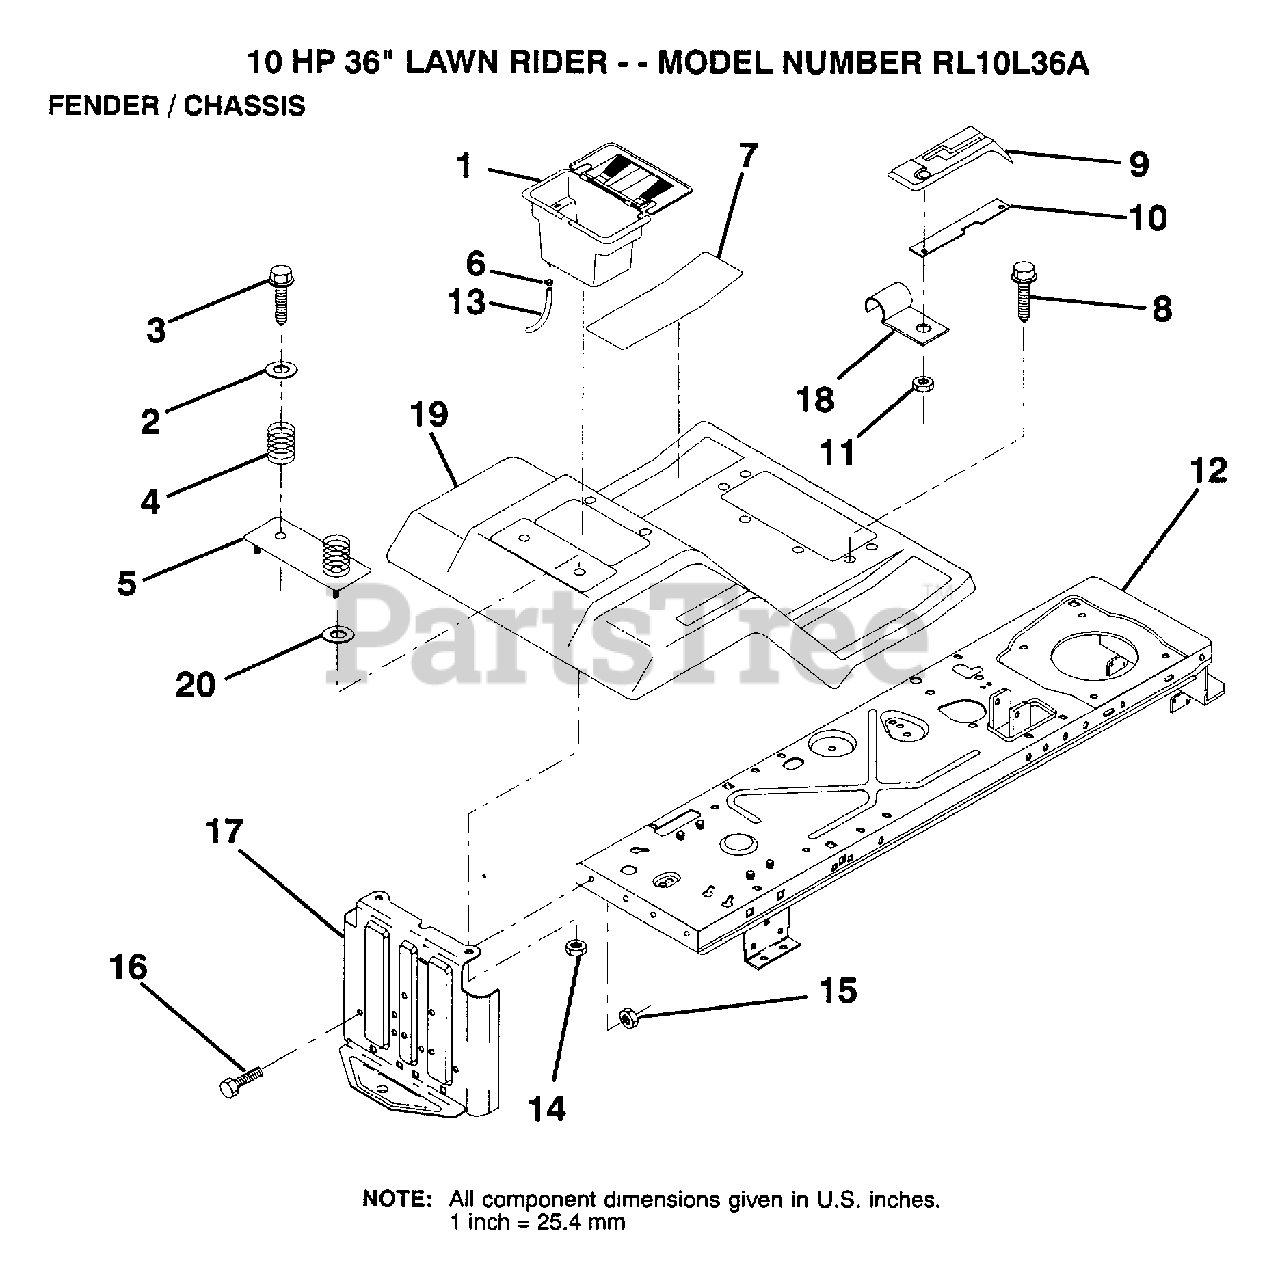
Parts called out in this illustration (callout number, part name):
2	WASHER
3	SCREW
4	SPRING COMPRESSIO
5	"PLATE, BATTERY"
6	HOSE CLAMP T
7	PAD FOOTREST
8	SCREW
9	CONSOLE SHFT 4SP
11	NUT
14	NUT
16	BOLT
17	DRAWBAR
18	"CLIP,INSULATOR"
